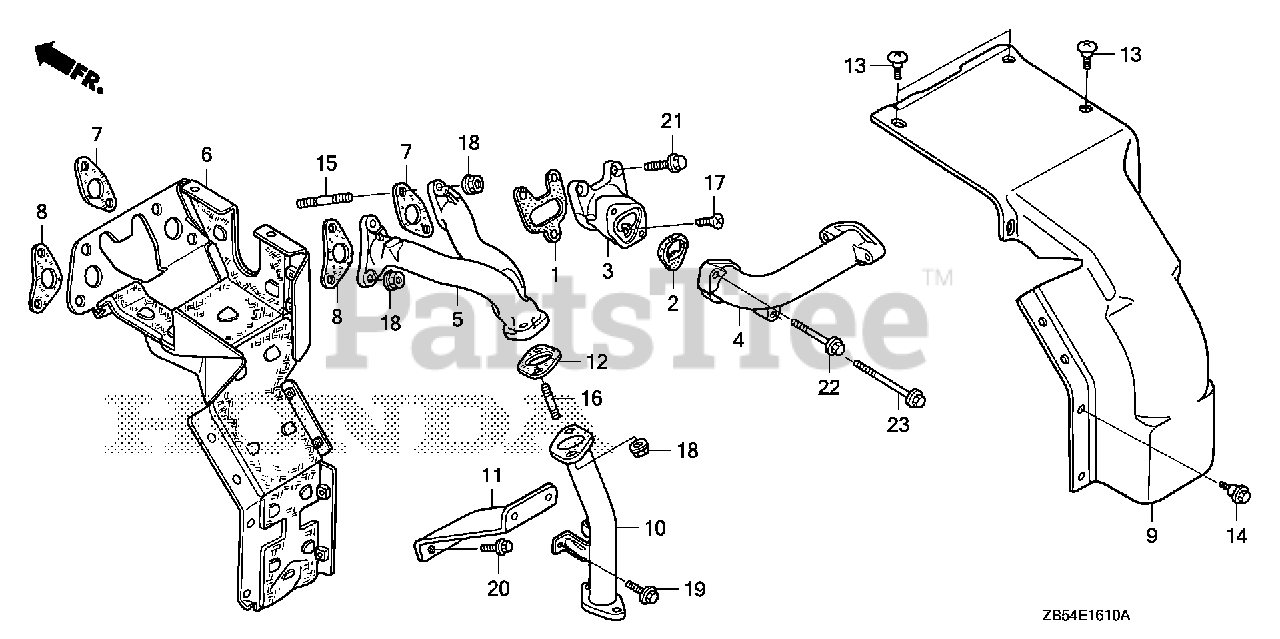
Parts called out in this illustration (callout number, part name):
1	GASKET, IN. MANIFOLD
2	GASKET, ELBOW
3	ELBOW, IN. MANIFOLD
4	MANIFOLD, IN.
5	MANIFOLD, EX.
6	COVER, EX. IN.
7	GASKET B, EX. PIPE
8	GASKET A, EX. PIPE
9	COVER, EX. OUTLET
11	STAY, EX. PIPE
12	GASKET, MUFFLER
13	BOLT, FAIRING (6MM)
14	BOLT, FLANGE (6MM)
15	BOLT, STUD (8X22)
16	BOLT, STUD (8X25)
17	SCREW, OVAL (6X25)
18	NUT, FLANGE (8MM)
19	BOLT, FLANGE (6X12) Use up to Engine SN 1543277.
20	BOLT, FLANGE (6X16) Use from Engine SN 2056820.
21	BOLT, FLANGE (6X25)
22	BOLT, FLANGE (6X30)
23	BOLT, FLANGE (6X55)
